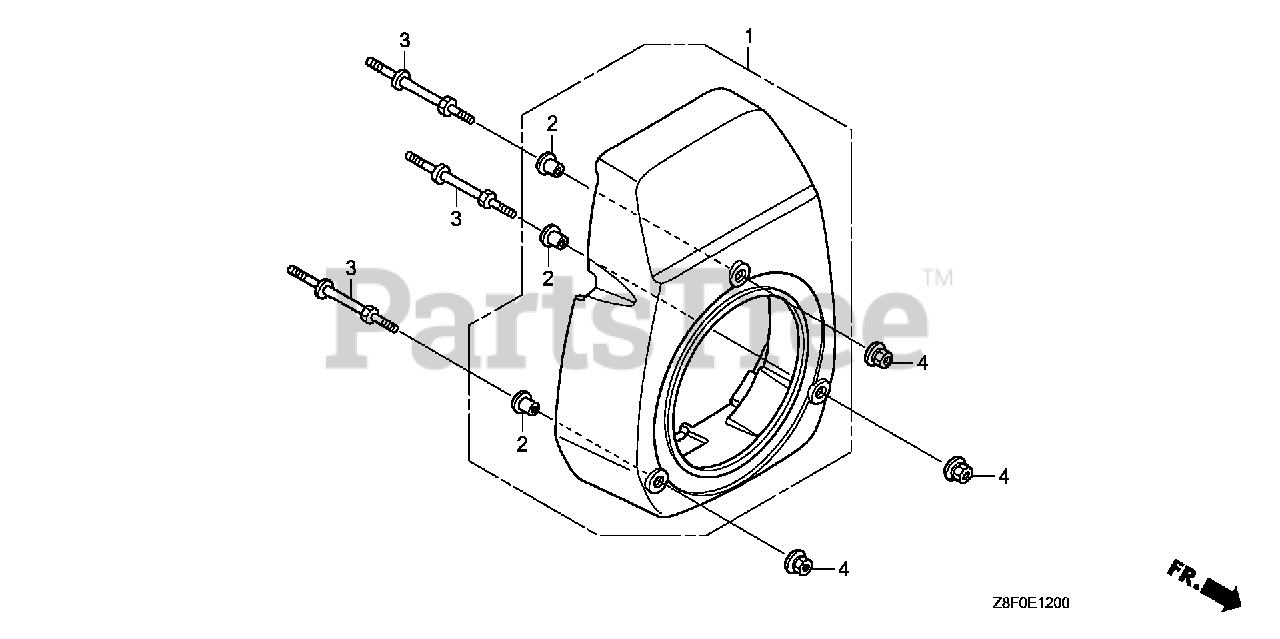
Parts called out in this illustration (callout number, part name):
1	COVER, FAN *NH1* (BLACK)
1	COVER, FAN *R280* (POWER RED)
2	COLLAR, FAN COVER (Honda Code 5580527). (N/A: SEE ASSEMBLY)
3	BOLT, STUD
4	NUT, FLANGE (6MM)
